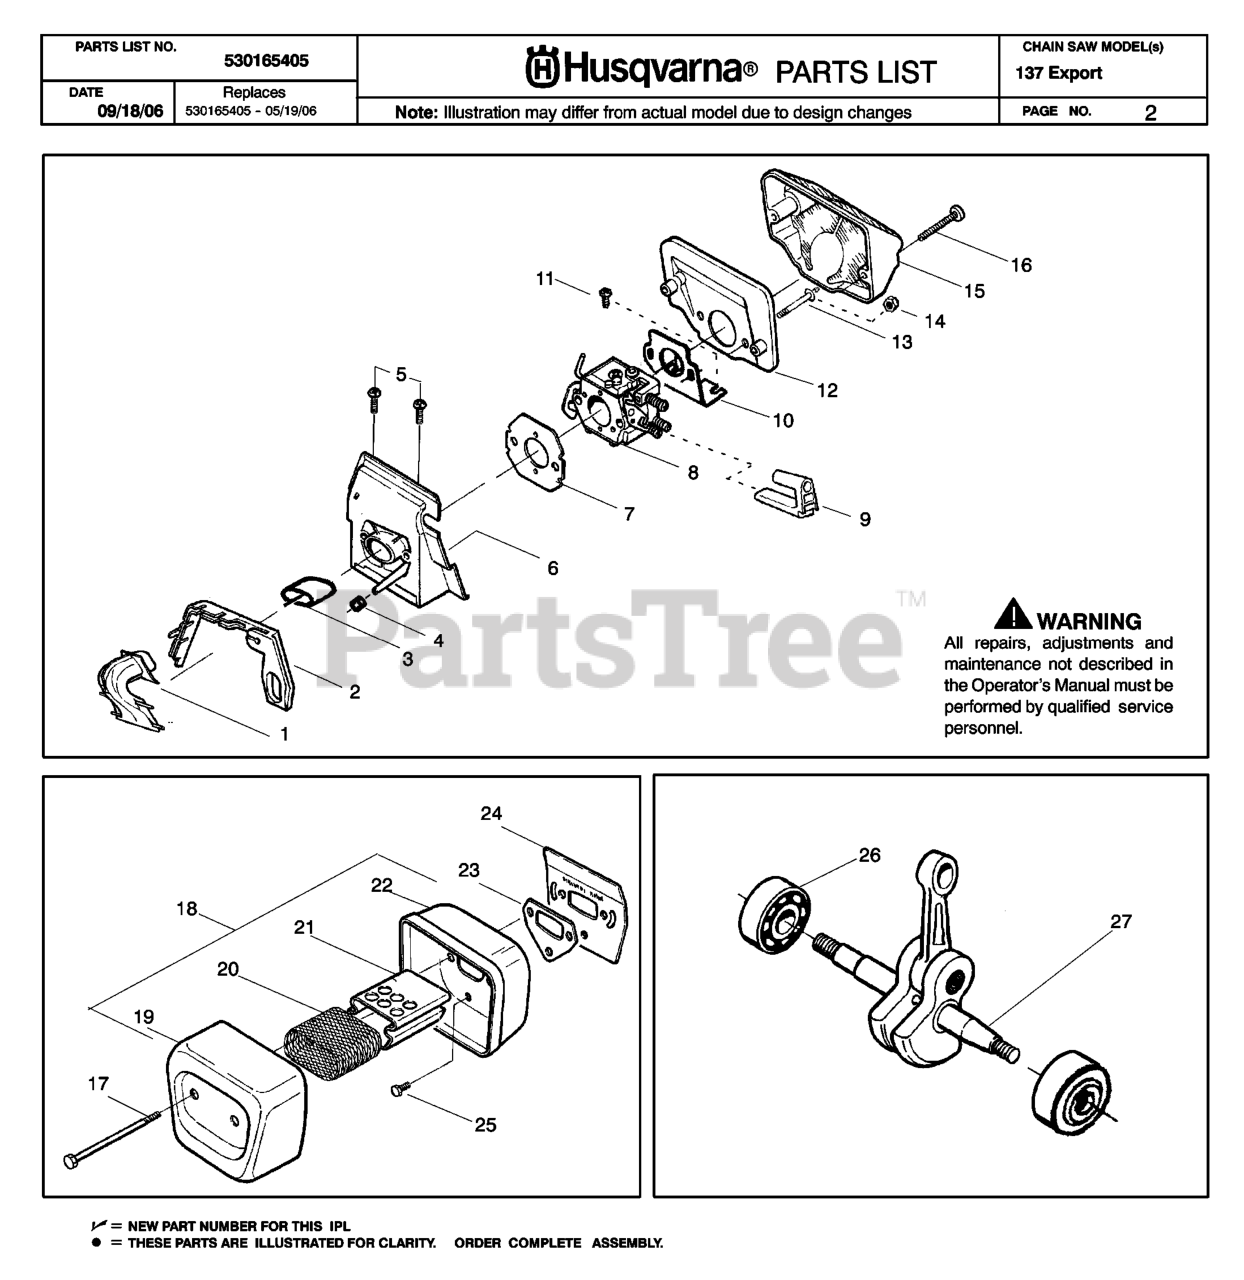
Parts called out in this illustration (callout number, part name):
1	GEARHEAD
2	GEARHEAD NUT - BRUSHCUTTER
3	SUPPORT FLANGE
4	WASHER
5	DRIVE DISC
6	RETAINING RING SGH 28
7	BEARING
8	BALL BEARING 8X22X7/608Z
12	BALL BEARING 24X9X1/609ZR
14	RETAINING RING
15	RETAINING RING
16	CLAMP
18	SCREW M6S 6X20
